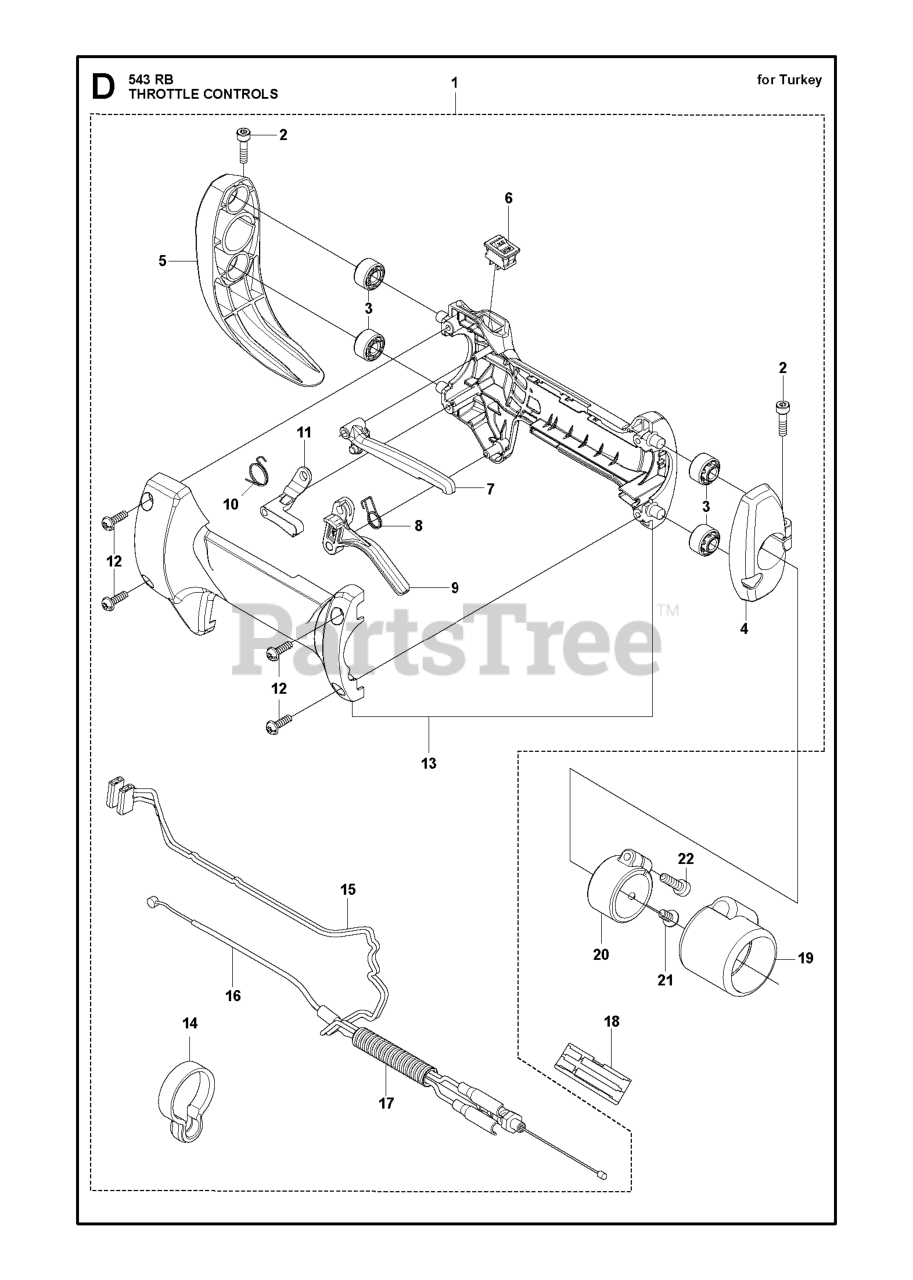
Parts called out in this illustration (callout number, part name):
2	BOLT
6	SWITCH
10	SPRING
11	LEVER JOINT
12	SCREW
22	BOLT TORX
